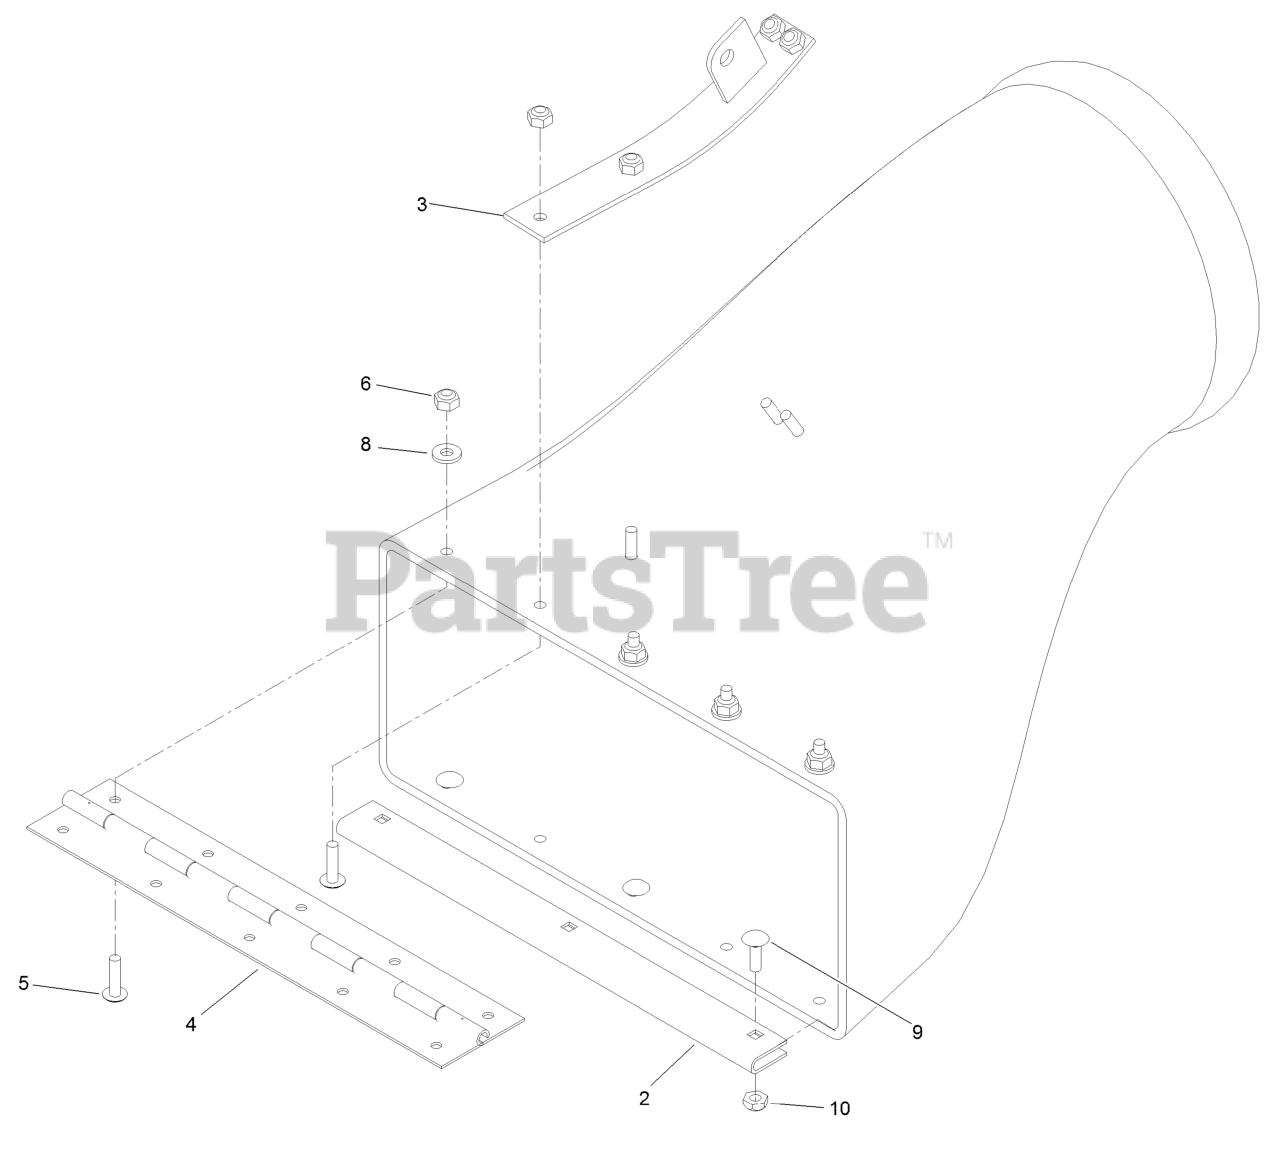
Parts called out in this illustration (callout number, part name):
2	GUARD-PLENUM
3	MOUNT-SPRING
4	HINGE-PIANO
5	SCREW-HEAD, TRUSS
6	NUT-LOCK, NI
8	WASHER-FLAT
9	BOLT-CARR
10	NUT-LOCK, NI
